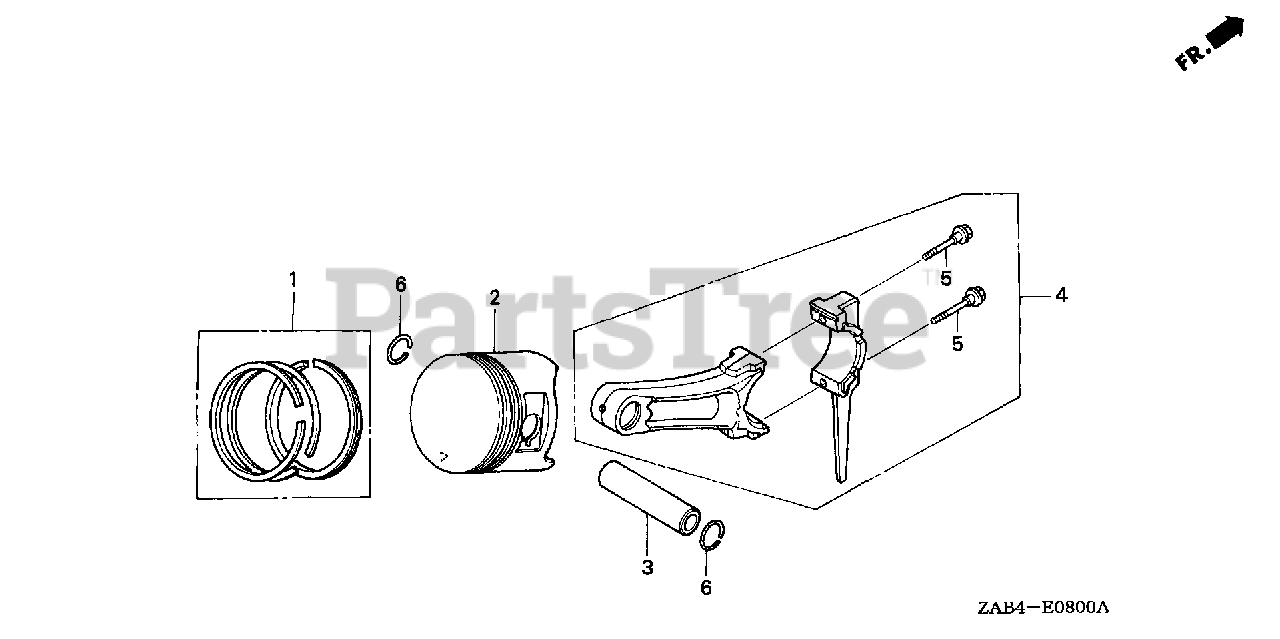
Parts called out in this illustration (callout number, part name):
1	RING SET, PISTON (STD)
1	RING SET, PISTON (OS 0.25)
1	RING SET, PISTON (OS 0.50)
1	RING SET, PISTON (0.75)
2	PISTON (STD)
2	PISTON (OS 0.25)
2	PISTON (OS 0.50)
2	PISTON (0.75)
3	PIN, PISTON
4	ROD ASSY., CONNECTING (STD)
4	ROD ASSY., CONNECTING
5	BOLT, CONNECTING ROD
6	CLIP, PISTON PIN (20MM)
